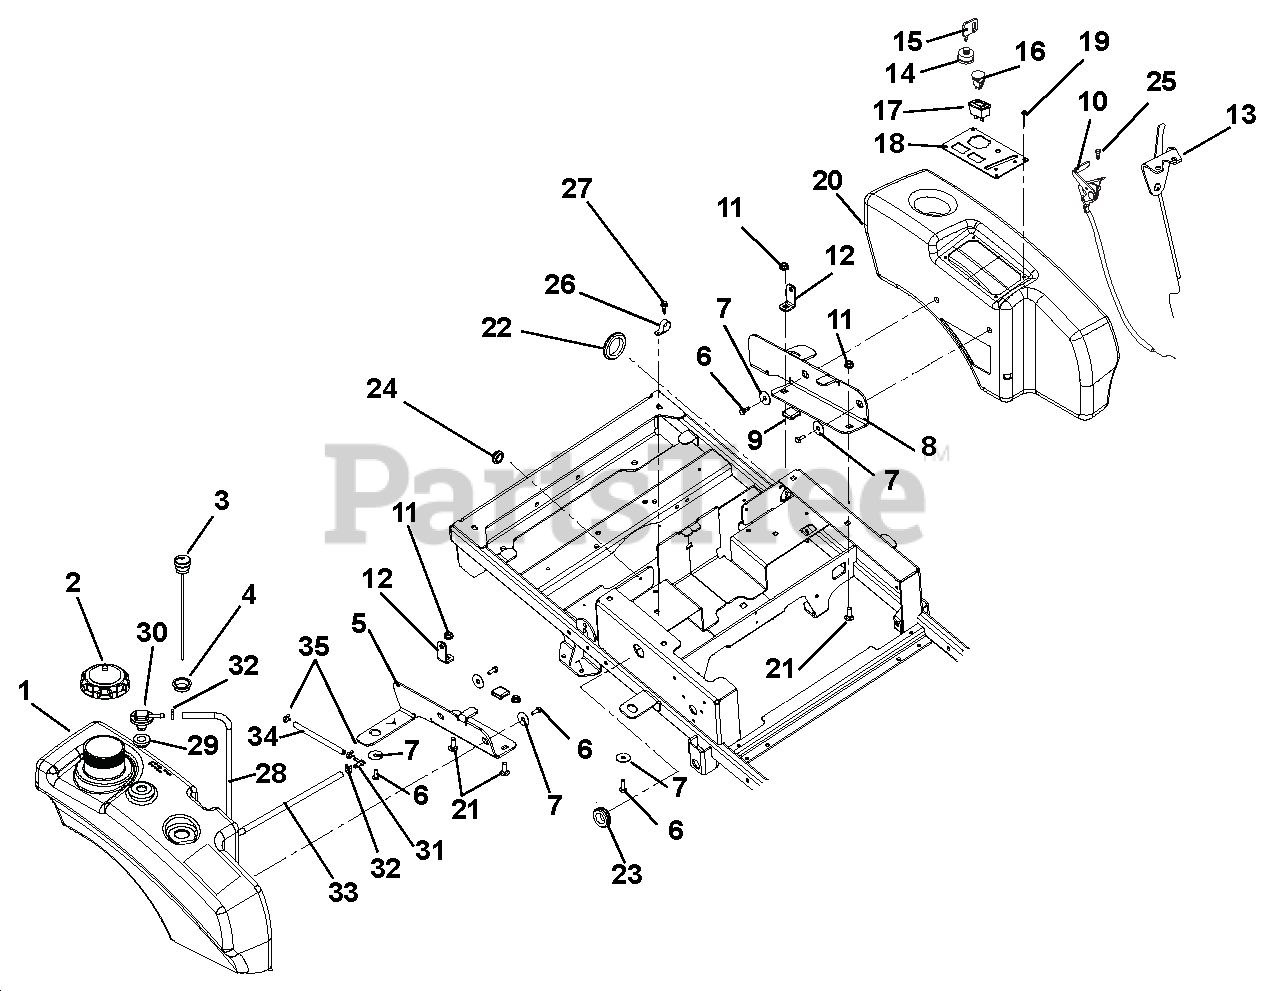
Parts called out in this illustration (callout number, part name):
1	TANK, XL NON-PERM ASSEMBLY
2	CAP, FUEL VENTIN AUTOLOCK
3	GAUGE, REMOTE FUEL 10.0"
4	GROMMET, FUEL GAGE
5	BRKT, RH REAR TANK MOUNT
6	BLT-SERHFWH .312-18X.50 YWZC
7	WSHR-FL-STL .347X1.254X.048YWZ
8	BRKT, LH REAR TANK MOUNT
9	GRIP, RUBBER (1.0X1.0X.187)BLK
10	CABLE, XL THROTTLE
11	@NUT-LK-NYL-FLG .38-16 YWZC
12	BRKT, HOOD PIVOT
13	CABLE, XL CHOKE
14	KEY SWITCH
15	KEY -W/CAP
16	SWITCH, CLUTCH
17	METER, HOUR W/MAINTENANCE
18	CONTROL PANEL
19	SCR-HEX .25X14-.75
20	FENDER, XL
21	@BLT-RDHDSQNK .38-16X1.00 G5YZ
22	GROMMET 1.70ID X 2.0OD
23	GROMMET 1.0ID X 1.38 OD
24	GROMMET,RUBBER 5/8 ID/1.13 OD
25	@SCR-TAP 10-24X.50 HWH TR YWZC
26	CLAMP, CUSHIONED STEEL .75
27	@SCR-TAP .38-16X.50 HWH TR YWZ
28	ASM, FUEL PICK-UP - XL
29	GROMMET, REMOTE VENT NITRILE
30	VENT, ROLL-OVER (.25"ID HOSE)
31	FITTING-3/16X1/4 90DEGREE VAC
32	CLAMP, FUEL LINE
33	HOSE, .25 LOW-PERM BULK GAS
34	HOSE, .188 LOW-PERM BULK GAS
35	CLAMP-HOSE, SPRING .188
